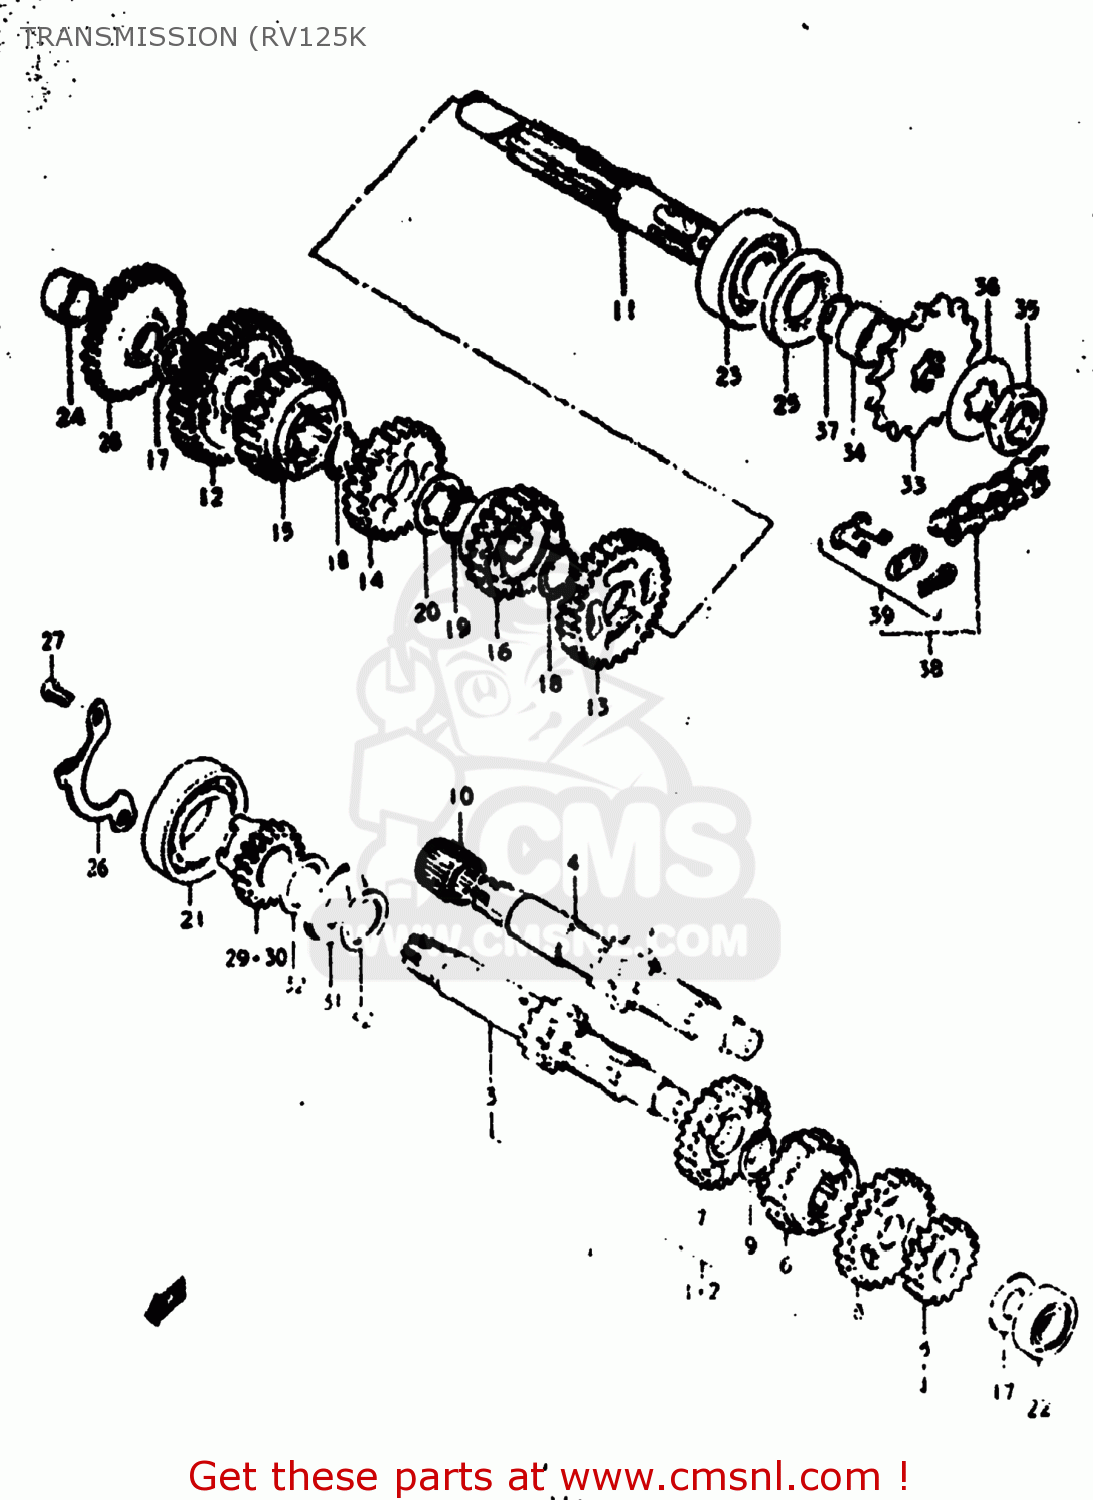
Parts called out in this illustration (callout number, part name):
1	SHAFT,COUNTER
2	SHAFT,COUNTER
3	SHAFT,COUNTER
4	SHAFT,COUNTER
5	GEAR,2ND DRIVE
6	GEAR,THIRD DRIVE
7	GEAR,FOURTH DRIVE
8	GEAR,FIFTH DRIVE
9	CIRCLIP
10	BEARING(19.2X23.2X19)
11	SHAFT,DRIVE
12	GEAR,1ST DRIVEN
13	GEAR,SECOND DRIVEN
14	GEAR,THIRD DRIVEN
15	GEAR,FOURTH DRIVEN
16	GEAR,FIFTH DRIVEN
17	WASHER
18	CIRCLIP
19	CIRCLIP
20	CLUTCH SLEEVE HUB WASHER
21	BEARING, RH
22	BEARING
23	BEARING
24	BUSHING
25	OIL SEAL (25X44X7)
26	RETAINER,CNTR SHAFT BEARING
27	SCREW
28	GEAR,KICK STARTER IDLE
29	GEAR,KICK STARTER DRIVE
30	GEAR,KICK STARTER DRIVE
31	BEARING(21X32X2.85)
32	WASHER(21X30X0.8)
33	SPROCKET,ENGINE
34	SPACER(20X25X12.5)
35	NUT
36	WASHER,LOCK
37	O RING(D:1,ID:19.5)
38	CHAIN ASSEMBLY,DRIVE
39	JOINT ASSEMBLY,CHAIN
